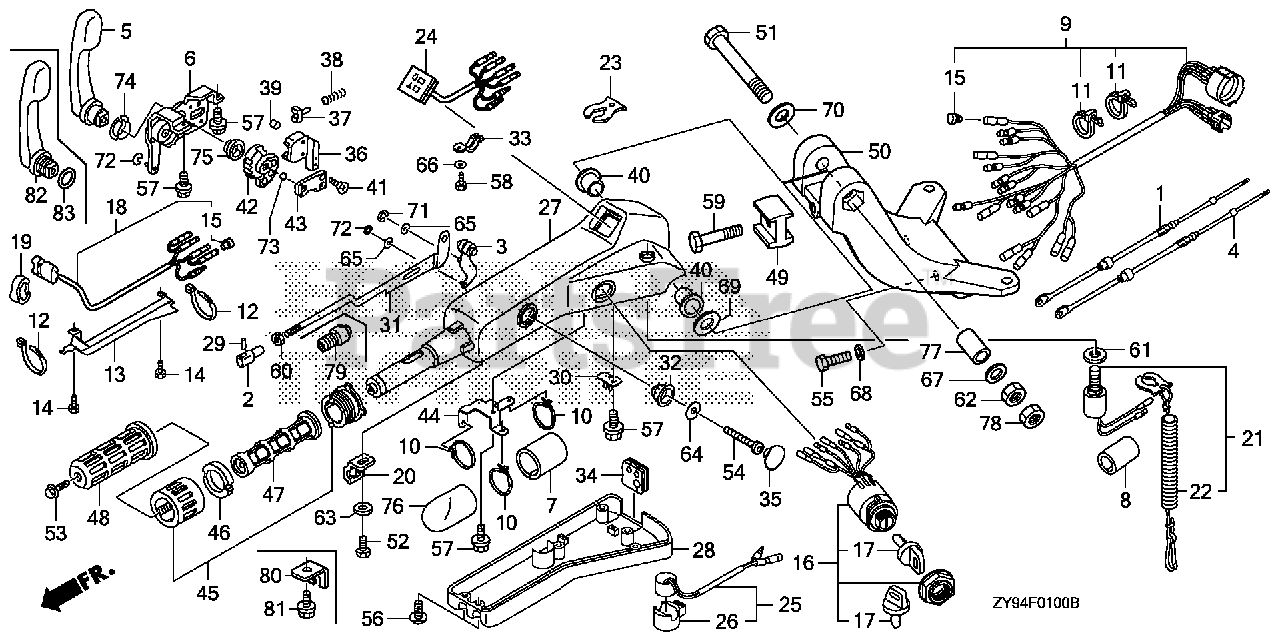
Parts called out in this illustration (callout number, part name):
1	CABLE, THROTTLE
2	PIVOT, THROTTLE CABLE
3	ARM, THROTTLE
4	CABLE, SHIFT
5	LEVER, SHIFT
6	FRAME ASSY., SHIFT
7	TUBE (38.1X40)
9	CABLE ASSY., LONG HANDLE (A)
10	BAND (CONVEX CV-150)
11	BAND (CONVEX CV-200)
12	BAND (CONVEX)
13	COVER, WIRE
15	PLUG, CONNECTOR (INNER) (TROLLING CONTROL)
16	SWITCH ASSY., COMBINATION
17	KEY ASSY., COMBINATION SWITCH (35100-ZV5-003 ONLY) DUAL QTY = (4) (SINGLE)
18	SWITCH ASSY., POWER TILT
20	HOLDER, SWITCH
21	SWITCH ASSY., EMERGENCY STOP
22	WIRE, EMERGENCY (SINGLE) (DUAL)
23	CLIP, EMERGENCY LOCK
24	LAMP ASSY., INDICATOR
25	BUZZER ASSY., WARNING
26	SUSPENSION, WARNING BUZZER
27	HOUSING *NH282MU* (OYSTER SILVER METALLIC-U)
28	COVER, HANDLEBAR (LOWER)
29	PIN, THROTTLE CABLE
30	BRACKET, CABLE
31	PLATE ASSY., LOCK
33	PLATE, GUIDE
36	GUIDE, SPRING
38	SPRING, COIL
40	BUSH, HANDLEBAR
41	SCREW (M5X14)
42	GEAR, SHIFT
43	PLATE, BALL GUIDE
45	GRIP ASSY., THROTTLE FRICTION
46	PAD, THROTTLE FRICTION
47	PIPE, GRIP
48	RUBBER, GRIP
49	BLOCK, HEIGHT ADJUSTER
50	BRACKET B, STEERING *NH282MU* (OYSTER SILVER METALLIC-U)
51	BOLT, HEX. (12X80)
52	BOLT (M5X8)
53	BOLT, FLANGE (6X12) Use from Frame SN 1005249.
54	BOLT (M8X50)
55	BOLT, HEX. (10X32)
56	BOLT (M5X12)
57	BOLT (M6X12)
58	BOLT (M5X12)
59	BOLT, FLANGE (8X28)
60	NUT, HEX. (5MM)
61	NUT, HEX. (16MM) DUAL QTY = (2) (SINGLE)
62	NUT, HEX. (12MM)
63	WASHER (5MM)
64	WASHER (8MM)
65	WASHER (10MM)
66	WASHER (5MM)
67	WASHER, WAVE (14MM)
68	WASHER (10MM)
69	WASHER, PLAIN (12MM)
70	WASHER, PLAIN (12MM)
73	BALL, STEEL
74	BEARING
76	TUBE, CORD (40MM)
77	COLLAR, DISTANCE (12.2X23X16)
78	NUT, HEX. (12MM)
79	ROD, GROMMET
80	CLAMP, BRACKET
81	BOLT (M6X12)
82	LEVER, SHIFT
83	O-RING (20.6X1.9)
